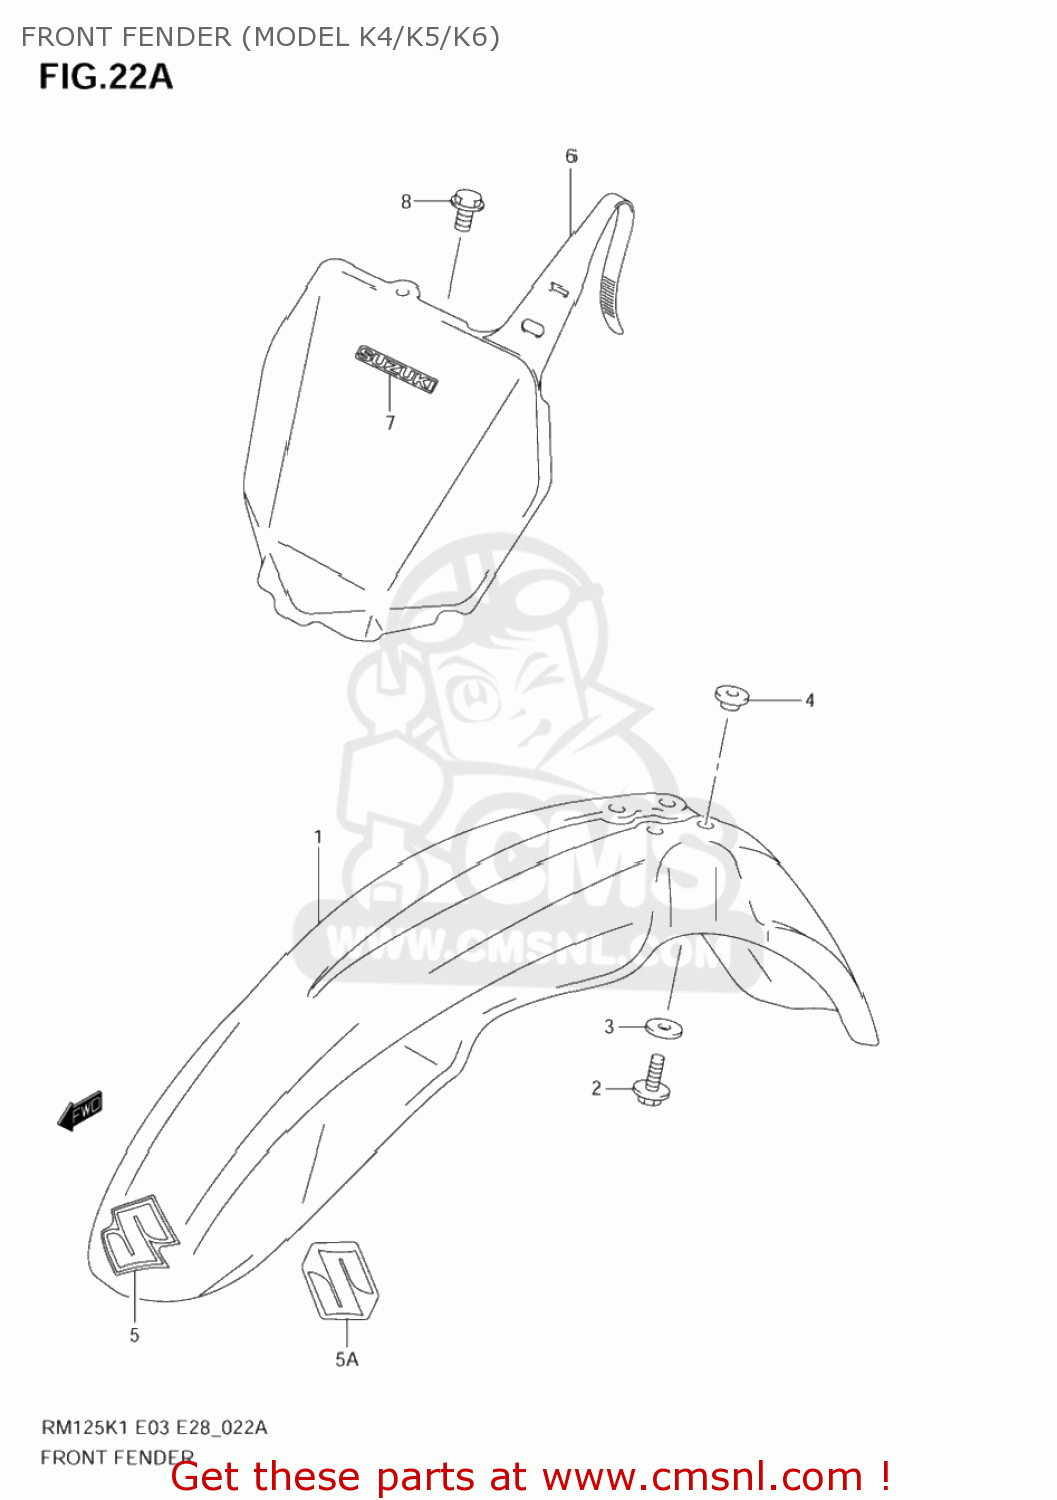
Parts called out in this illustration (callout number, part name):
1	FENDER,FR
2	BOLT
3	WASHER(6.5X28X1.6)
4	WASHER
5	EMBLEM,S
5A	EMBLEM,S
6	PLATE,NUMBER F
7	EMBLEM,HEADLAMP COVER
8	BOLT(6X12)
